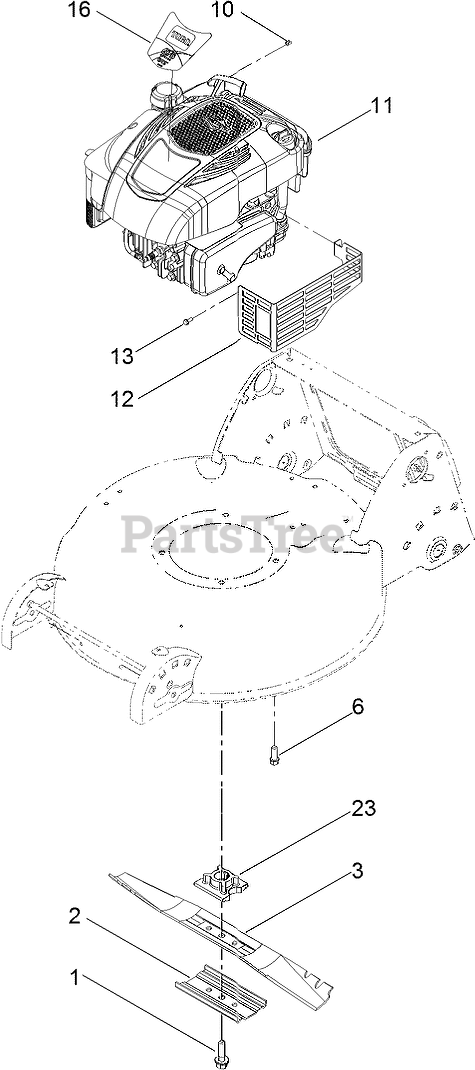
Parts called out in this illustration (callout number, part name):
1	BOLT-BLADE
2	SUPPORT-BLADE
3	BLADE-21 INCH
6	SCREW-TAPTITE
10	STOP-ROPE
12	SHIELD-MUFFLER
13	SCREW-TAPTITE
16	DECAL-SHROUD
23	RETAINER-BLADE
